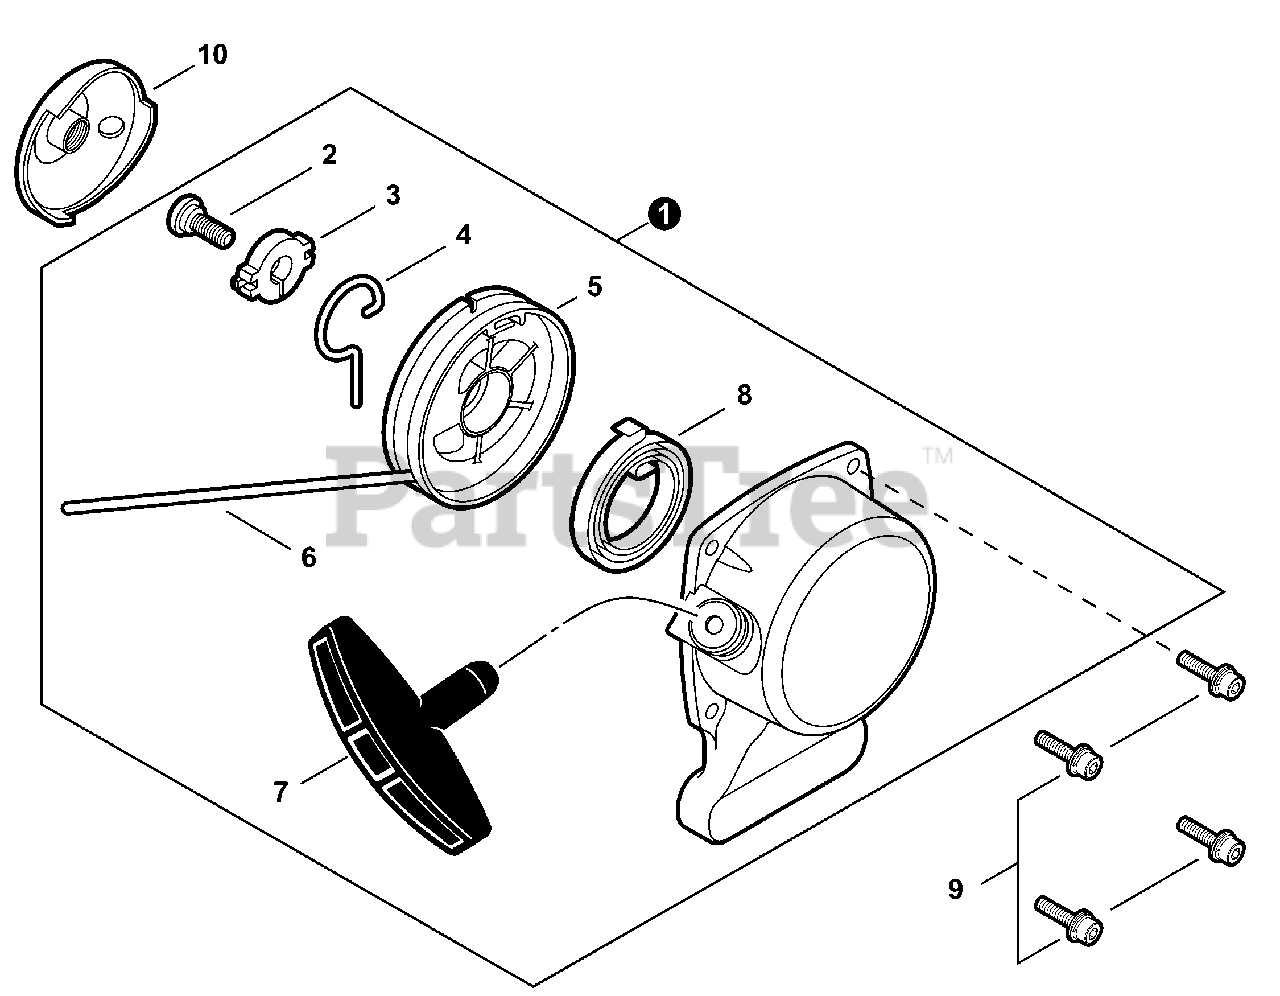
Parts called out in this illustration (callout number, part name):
1	STARTER ASSY, RECOIL
2	SCREW 5
3	WASHER 5
4	ARM, SWING
5	REEL, ROPE
6	ROPE, STARTER
7	GRIP, STARTER
8	SPRING, RECOIL
9	BOLT M4×14
10	PULLEY, STARTER
